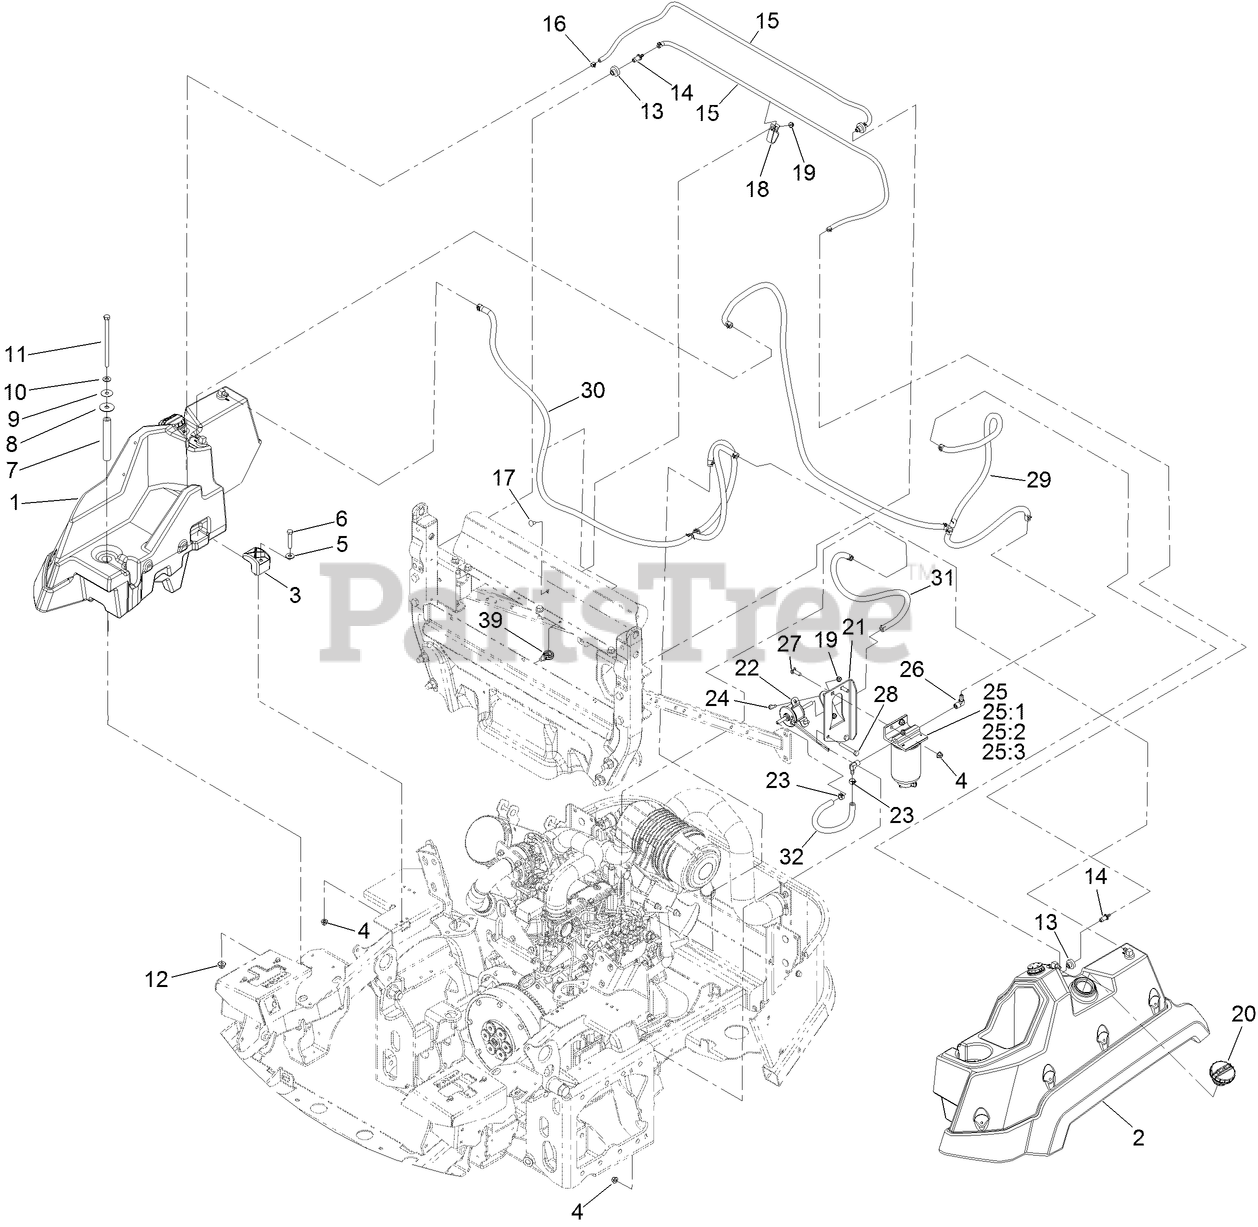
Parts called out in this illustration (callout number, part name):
1	RH FUEL TANK ASM
2	LH FUEL TANK ASM
4	NUT-HF, NI
5	WASHER-FLAT
6	SCREW-HH
7	TUBE-SPACER
8	WASHER-RUBBER
9	WASHER-PLAIN
10	WASHER-FLAT
11	SCREW-HH
12	NUT-HF, NI
13	BUSHING
14	FITTING-ORIFICE, STRAIGHT
15	HOSE-VENT, TANK
16	CLAMP-HOSE
17	SCREW-CARR
18	CLAMP-HOSE
19	NUT-HF
20	CAP-FUEL, DIESEL
21	BRACKET-FILTER AND PUMP, FUEL
22	PUMP-FUEL, ELECTRIC
23	CLAMP-HOSE
24	SCREW-HWH
25	SEPARATOR-FILTER
25	FUEL FILTER ASM
25:1	FILTER-SPIN ON
25:2	FILTER,FUEL
25:3	DECAL-FILTER
26	FITTING-HYD, 90
27	SCREW-CARR
28	SCREW-HH
29	LINE-FUEL, SUCTION
30	LINE-FUEL, RETURN
31	HOSE-FUEL
32	HOSE-FUEL
39	CLIP-TIE
